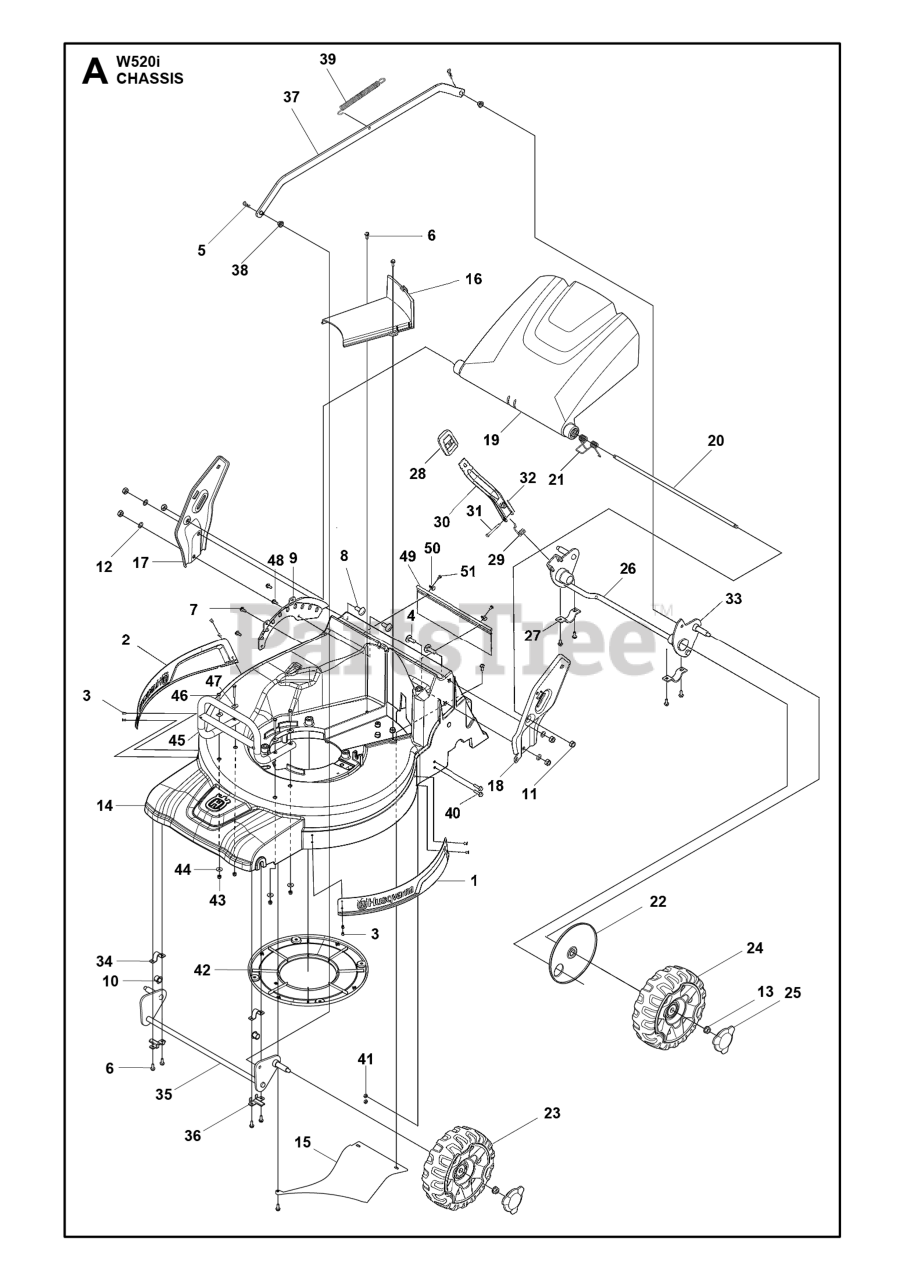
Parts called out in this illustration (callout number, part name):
3	Rivet
11	LOCKNUT M8
12	WASHER BRB 8.4X17
21	SPRING 51 CAST
33	Ball Bearings
39	SPRING HEIGHT ADJUSTER
40	SCREW M6S 5X20
43	LOCKNUT M6
46	Hex Head Capscrew, M6 X 1.00 X 40MM
51	SCREW ITXPANTT M5X10 ZPB (A00
